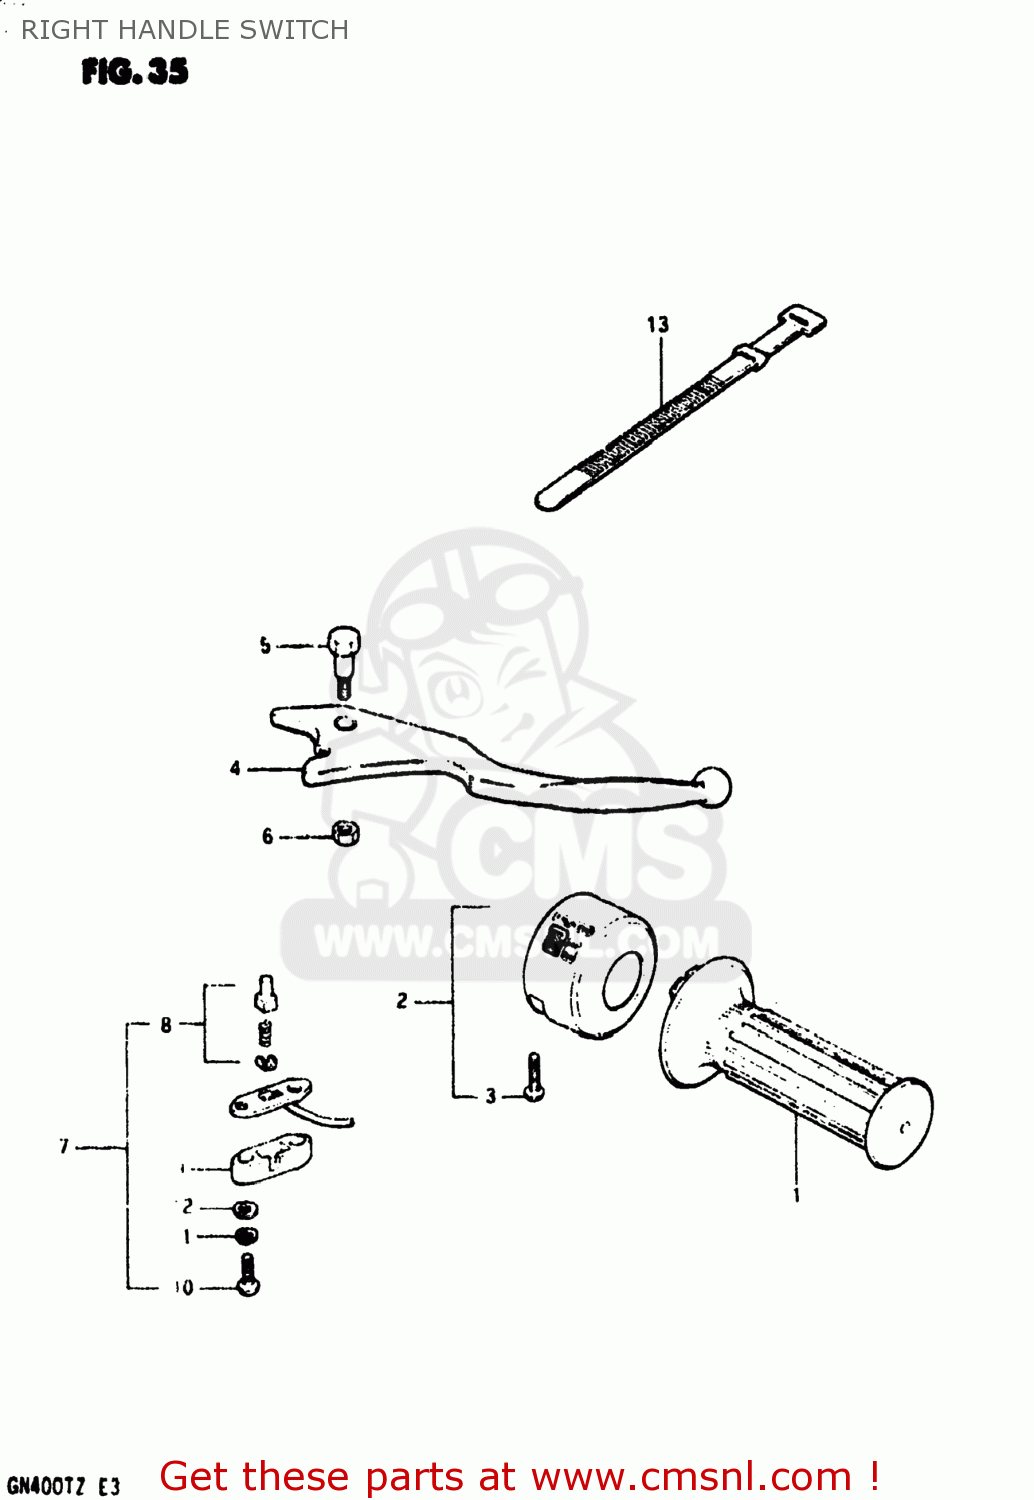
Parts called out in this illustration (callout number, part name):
1	GRIP,THROTTLE
2	CASE ASSEMBLY,THROTTLE
3	SCREW
4	LEVER,BRAKE
5	BOLT
6	NUT 6MM
7	SWITCH ASSEMBLY
8	CONTACT,SWITCH
9	COVER,FR BK TERMINAL BASE
10	SCREW
11	LOCK WASHER
12	WASHER
13	CLAMP(L:120)
